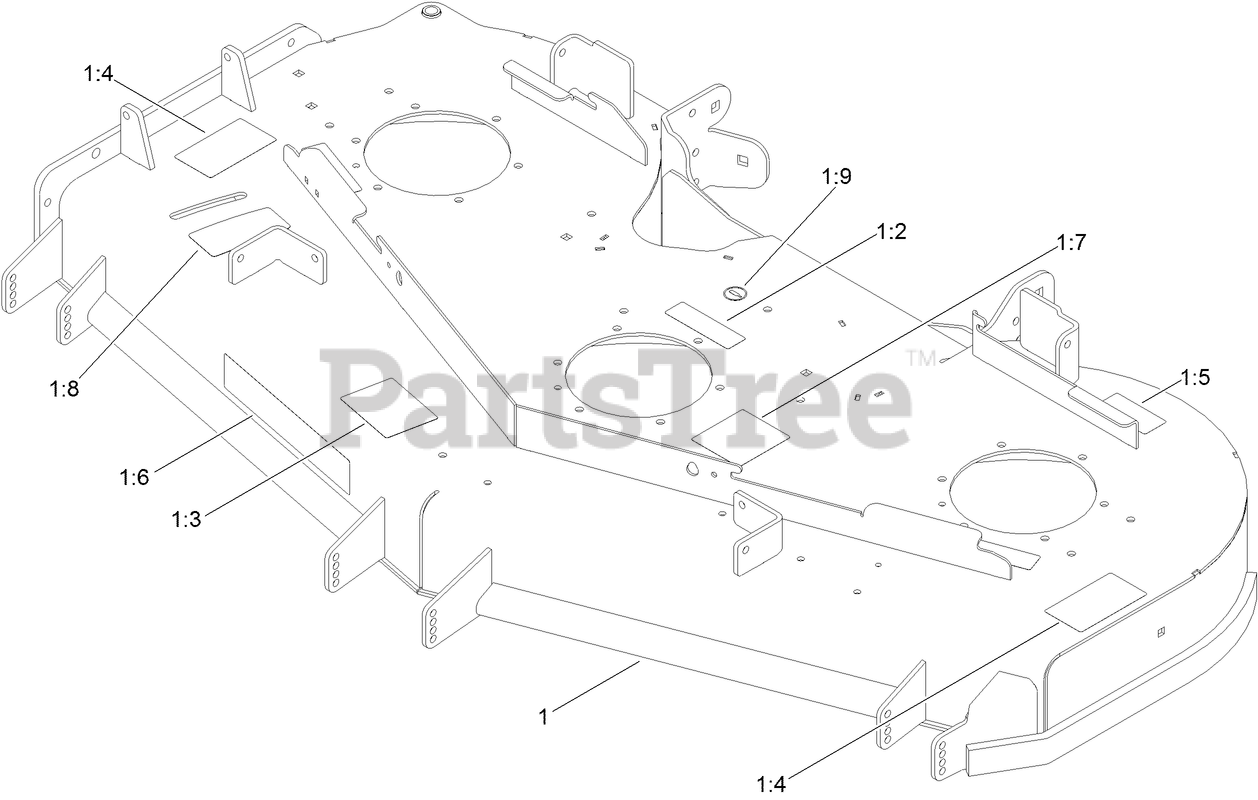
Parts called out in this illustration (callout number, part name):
1	DECK ASM
1:2	DECAL-COVER, MISSING
1:3	DECAL-SCALP, ANTI
1:4	DECAL-DANGER
1:5	DECAL-BOLT TORQUE
1:7	DECAL-ROUTING, DECK BELT
1:8	DECAL-ADJUSTMENT, BAFFLE
1:9	DECAL-GREASE
